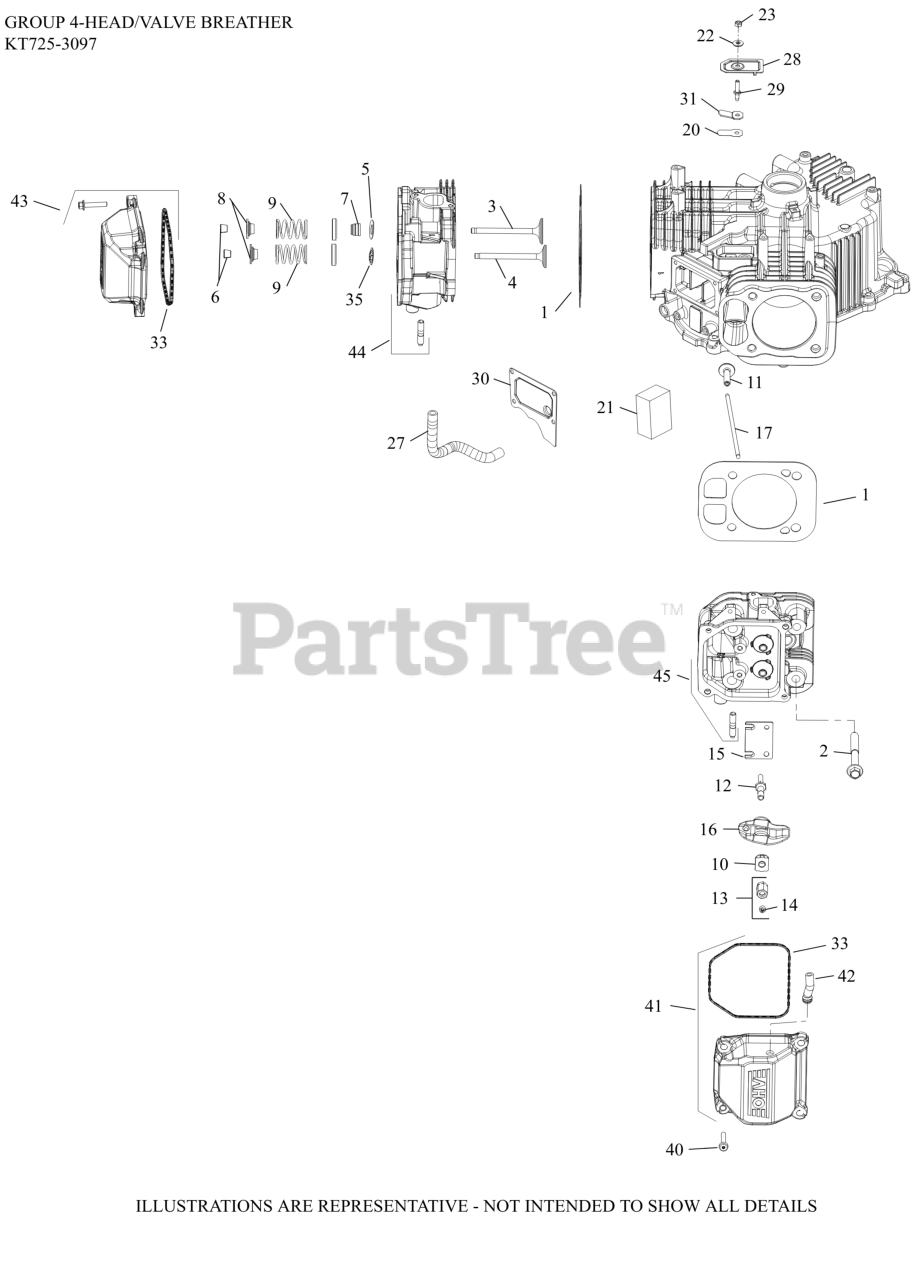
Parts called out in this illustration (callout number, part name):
1	KIT, CYLINDER HEAD GASKET
2	SCREW, FLG M10X1.5X90
3	VALVE, INTAKE
3	VALVE, INTAKE (.25) - (#2401702S)
4	VALVE, EXHAUST
4	VALVE, EXHAUST (.25)
5	SPACER (.010")
6	KIT, RETAINER
7	SEAL, VALVE BAND
8	CAP, VALVE SPRING
9	SPRING VALVE
10	PIVOT, ROCKER ARM
12	STUD, ROCKER
13	HEX NUT ASSEMBLY
14	SCREW, SET
15	PLATE, GUIDE
16	ARM, ROCKER
17	ROD, PUSH
20	REED, BREATHER
21	FILTER, BREATHER
22	WASHER, SEALING
23	NUT, LOCK M5X.8
27	HOSE, BREATHER
28	COVER, BREATHER REED
30	COVER, BREATHER MEDIA
31	RETAINER, REED
33	O-RING (YELLOW), VALVE CO
35	RETAINER, VALVE GUIDE (KM)
40	SCREW, PAN HEAD
41	KIT,BREATHER VALVE COVER (PLASTIC)
42	HOSE, FP-USE 32 326 07-S(PLASTIC COVERS)
43	KIT, VALVE COVER-PLAIN (PLASTIC)
44	HEAD, ASSEMBLY CYLINDER (#1)
45	HEAD, ASSEMBLY CYLINDER (#2)
